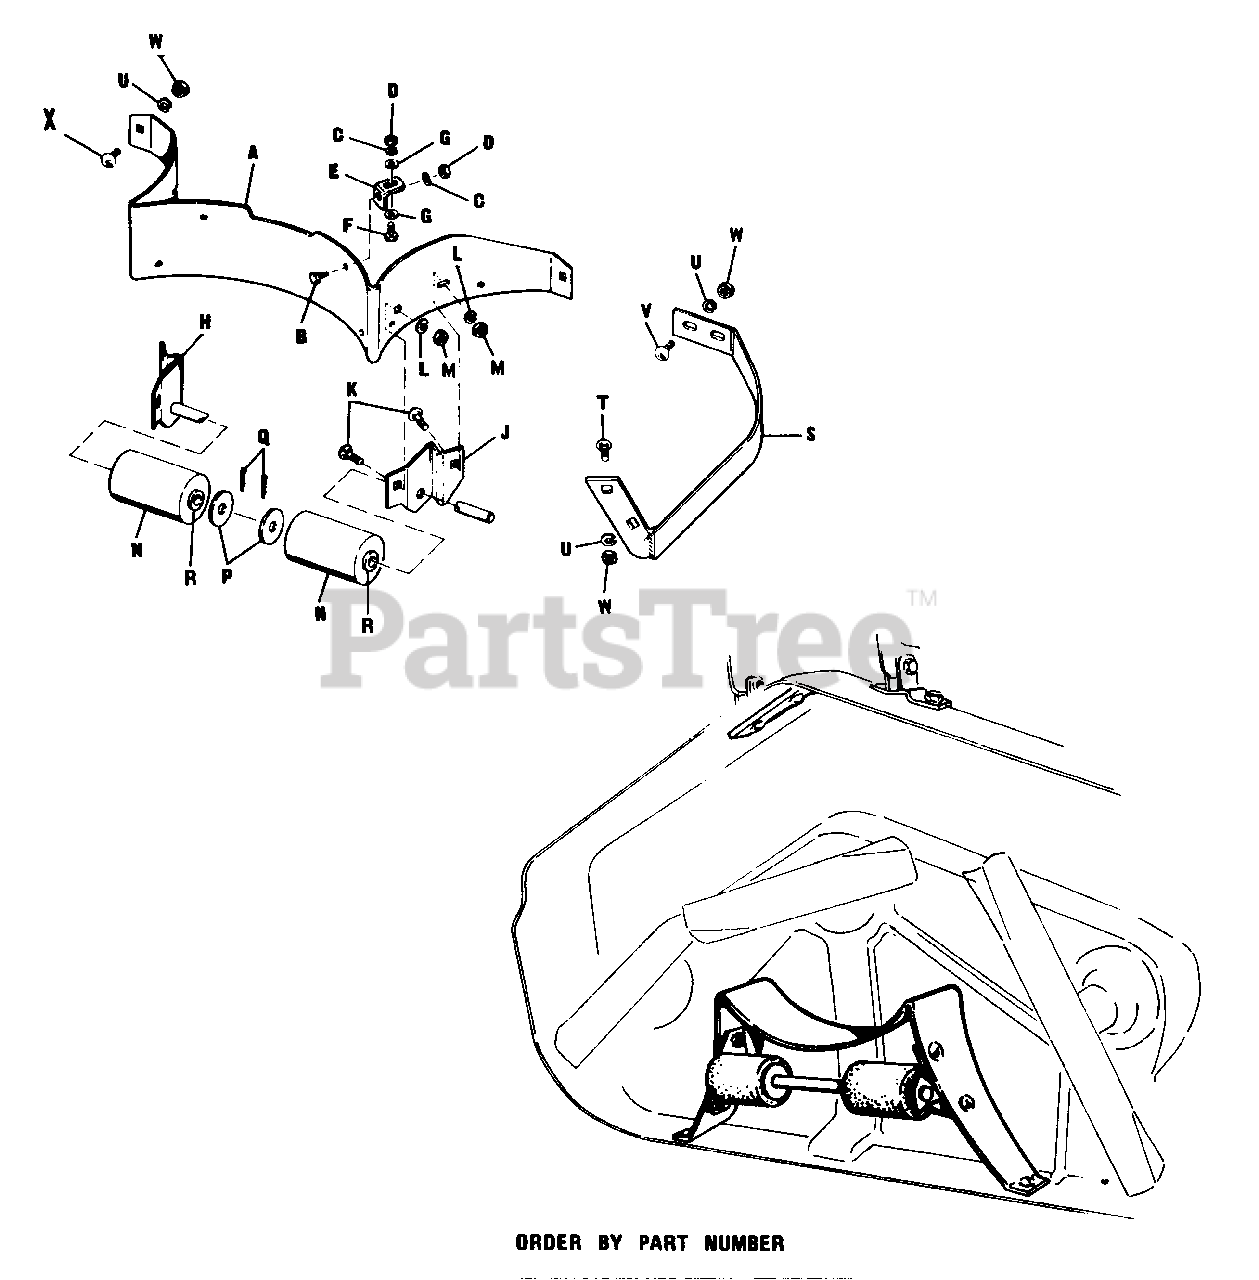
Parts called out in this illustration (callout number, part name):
B	Self Tap Hex. Screw, 1/4"-20 x 7/8"
C	Lock Washer, 1/4"
D	Full Hex. Nut, 1/4"-20
E	Baffle Clip
F	Hex. Cap Screw, 1/4"-20 x 5/8"
G	Plain Washer, 1/4"
H	Bracket & Shaft Assembly
J	L.H. Roller Bracket
K	Carriage Bolt, 5/16"-18 x 3/4"
L	Lock Washer, 5/16"
M	Full Hex. Nut, 5/16"-18
N	Roller Assembly W/Bushing
Q	Cotter Pin,3/16" x 1"
S	Housing Assembly Guard
T	Carriage Bolt, 3/8"-16 x 3/4"
U	Lock Washer 3/8"
V	Carriage Bolt, 3/8"-16 x 1"
W	Full Hex. Nut, 3/8"-16
X	Carriage Bolt, 3/8"-16 x 3/4" lg.
